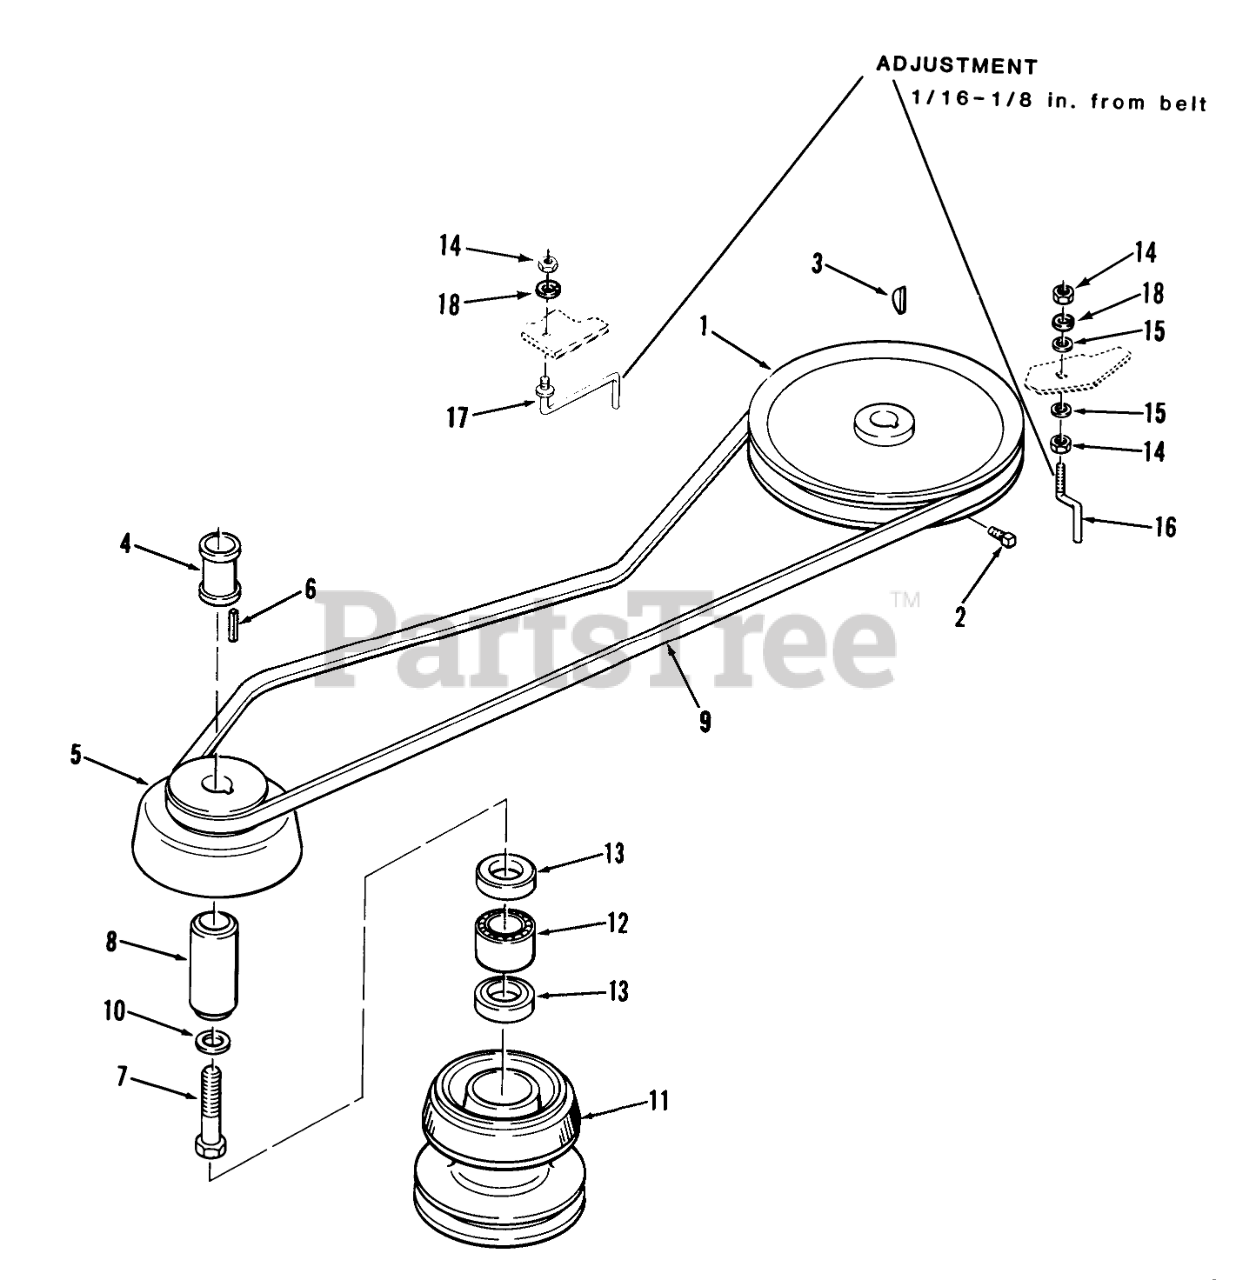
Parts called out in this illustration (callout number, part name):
1	PULLEY-TRANS
1	PULLEY-TRANSMISSION
2	Set Screw
3	KEY-HI-PRO
4	TUBE SPACER
5	PULLEY-ENGINE
7	HEX HD CAP SCREW
8	RACE BEARING
9	V-BELT
10	WASHER
11	Assy Pulley Mwr Dr
12	BRG-NEEDLE OPEN END
13	SEAL-OIL
14	Nut
15	WASHER 5/16 SAE
16	GUIDE-BELT
17	GUIDE-BELT
18	Lockwasher
